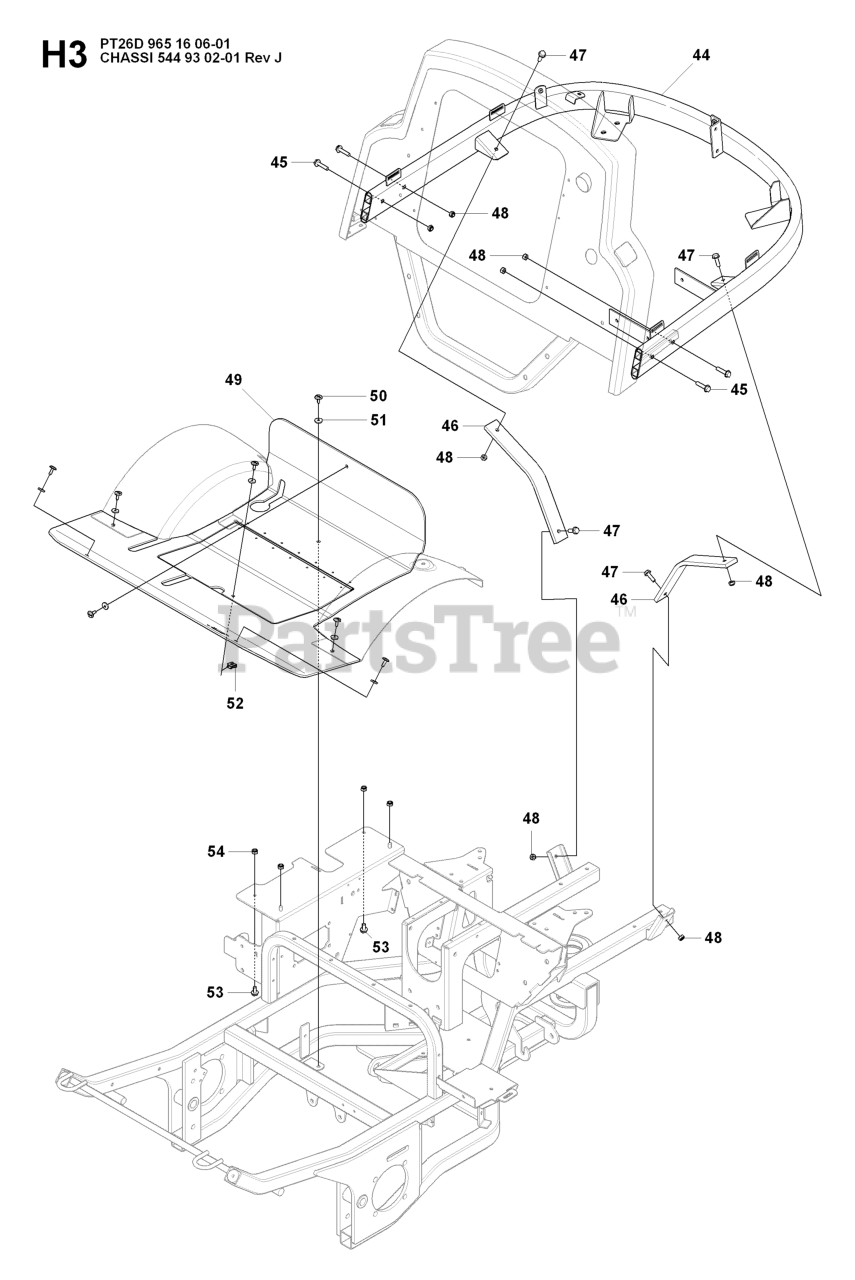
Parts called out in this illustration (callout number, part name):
2	STOP SLEEVE STEERING STOP
12	FRAME REAR
15	WASHER
19	SWING AXLE
21	NUT
23	BUSHING
24	GUIDE PLATE HYDRAULIC HOSES
34	LOCKNUT M8
35	FENDER LEFT
36	FENDER RIGHT
39	LOCKNUT M8
45	SCREW EHHFM
47	BOLT
48	LOCKNUT M8
